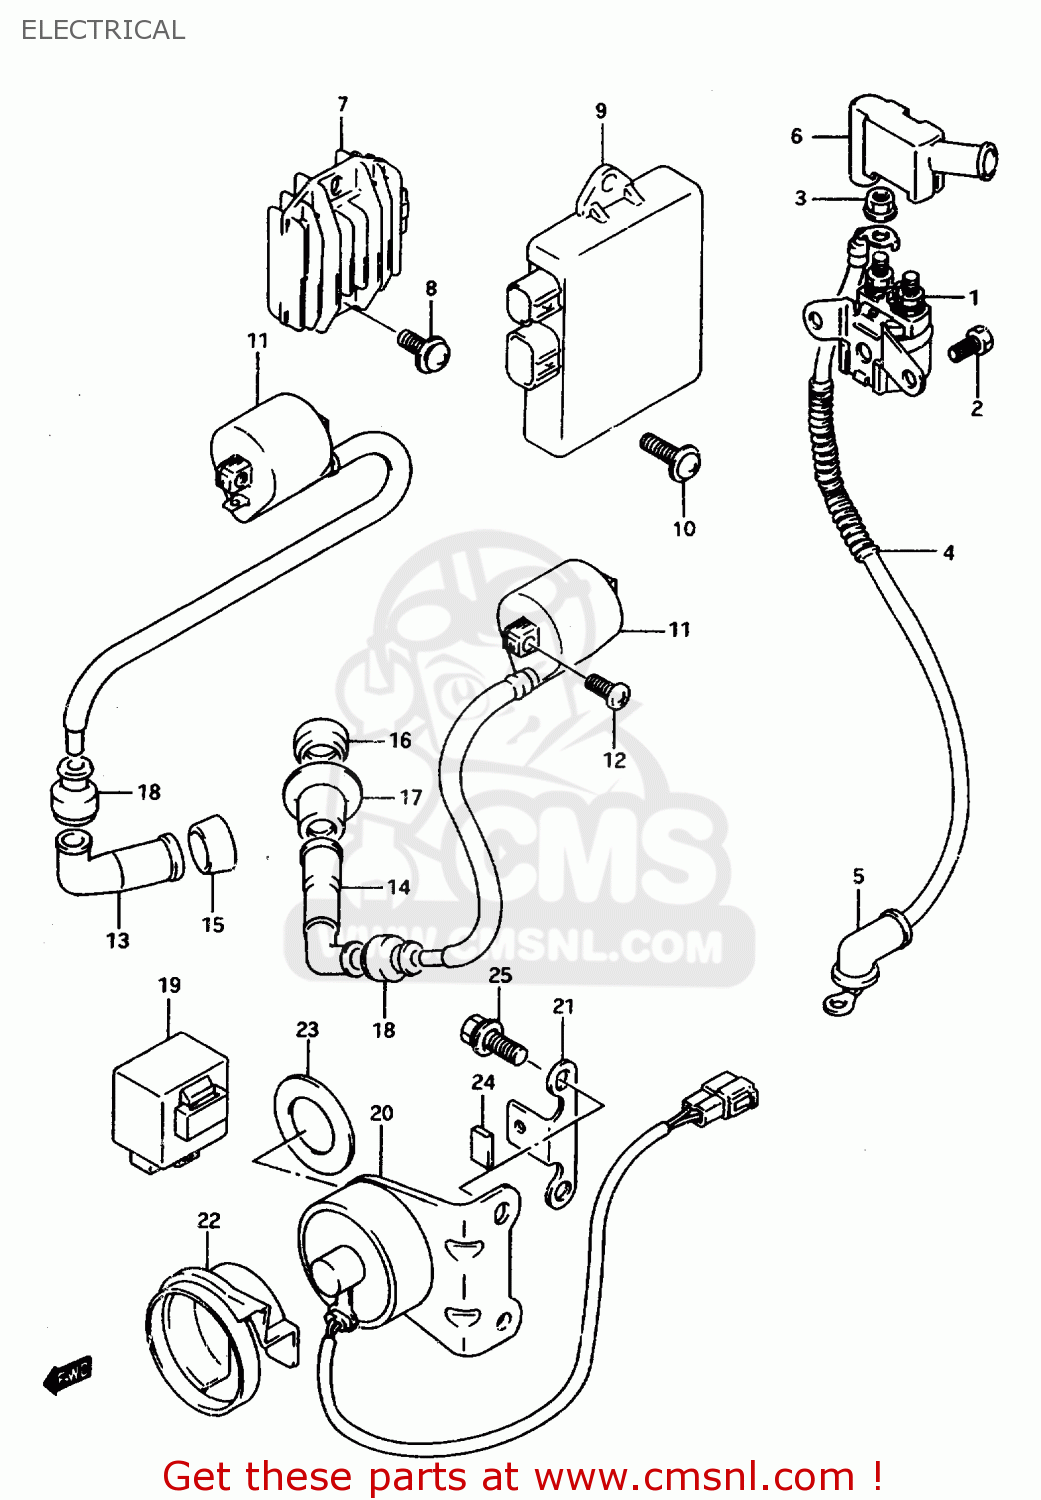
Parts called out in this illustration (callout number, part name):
1	RELAY ASSY,STARTING MOTOR
2	BOLT(6X8)
3	NUT
4	WIRE,STARTER MOTOR LEAD
5	CAP,STARTER MOTOR LEAD
6	CAP, STARTER RELAY
7	RECTIFIER ASSY
8	SCREW
9	CDI UNIT
10	SCREW
11	COIL ASSY,IGNITION
12	SCREW, 6X20
13	CAP,SPARK PLUG
14	CAP,SPARK PLUG
15	SEAL,SPARK PLUG CAP
16	SEAL,SPARK PLUG CAP
17	COVER,SPARK PLUG CAP,L
18	SEAL,HIGH TENSION CORD
19	CONTROL UNIT,DECOMP
20	SOLENOID ASSY,DECOMP
21	STOPPER,DECOMP
22	COVER DECOMP S
23	CUSHION,DECOMP
24	CUSHION,BATTERY(80X27X3)
25	BOLT
